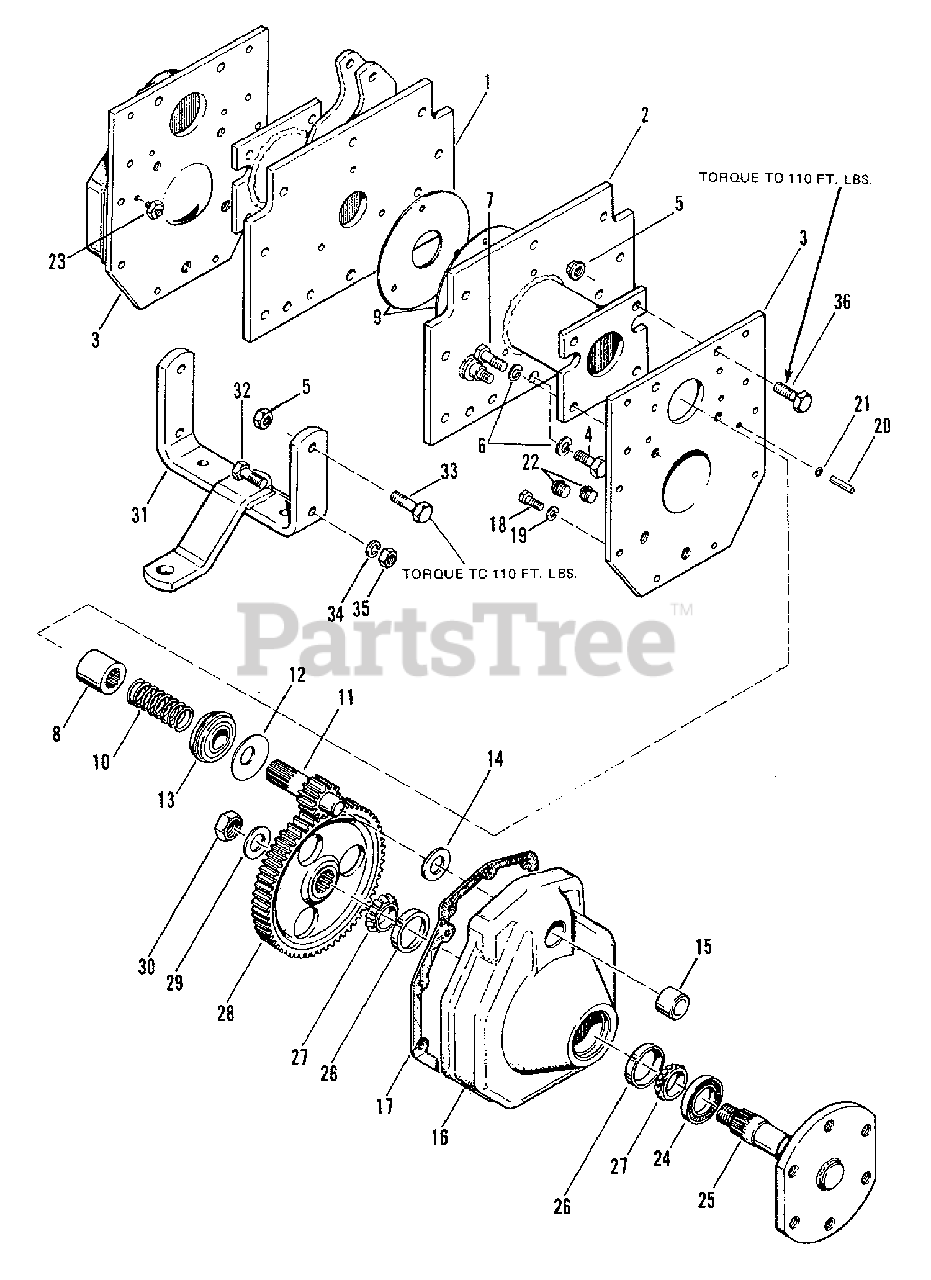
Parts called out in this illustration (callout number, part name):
1	EXTENSION, Axle, L.H.
2	EXTENSION, Axle, R.H.
3	PLATE, Housing
4	CAPSCREW, Hex, 1/2"-13 x 1-1/2" Lg.
5	NUT, Hex, Lock
6	LOCKWASHER, 1/2"
7	CAPSCREW, Hex, 1/2"-13 x 1" Lg.
8	COUPLE, Axle
9	PLATE, Shim
11	PINION, Bull
13	BEARING, Rear Axle
14	WASHER, Thrust
15	BEARING, Roller
16	HOUSING, Drop
18	CAPSCREW, Hex
19	LOCKWASHER, 3/8"
20	PIN, Roll
21	RING, "O"
22	PLUG, Pipe
23	VALVE, Relieft
25	REAR AXLE ASSEMBLY
26	CUP, Bearing
27	CONE, Bearing
28	GEAR, Bull
29	WASHER, Plain
30	LOCKNUT, Whiz
32	CAPSCREW, Hex, 1/2"-13 x 1-1/2" Lg.
33	CAPSCREW, Hex, 1/2"-13 x 1-3/4" Lg.
34	LOCKWASHER, 1/2"
35	NUT, Hex, 1/2"-13
36	CAPSCREW, Hex, 1/2"-13 x 1-1/2" Lg.
